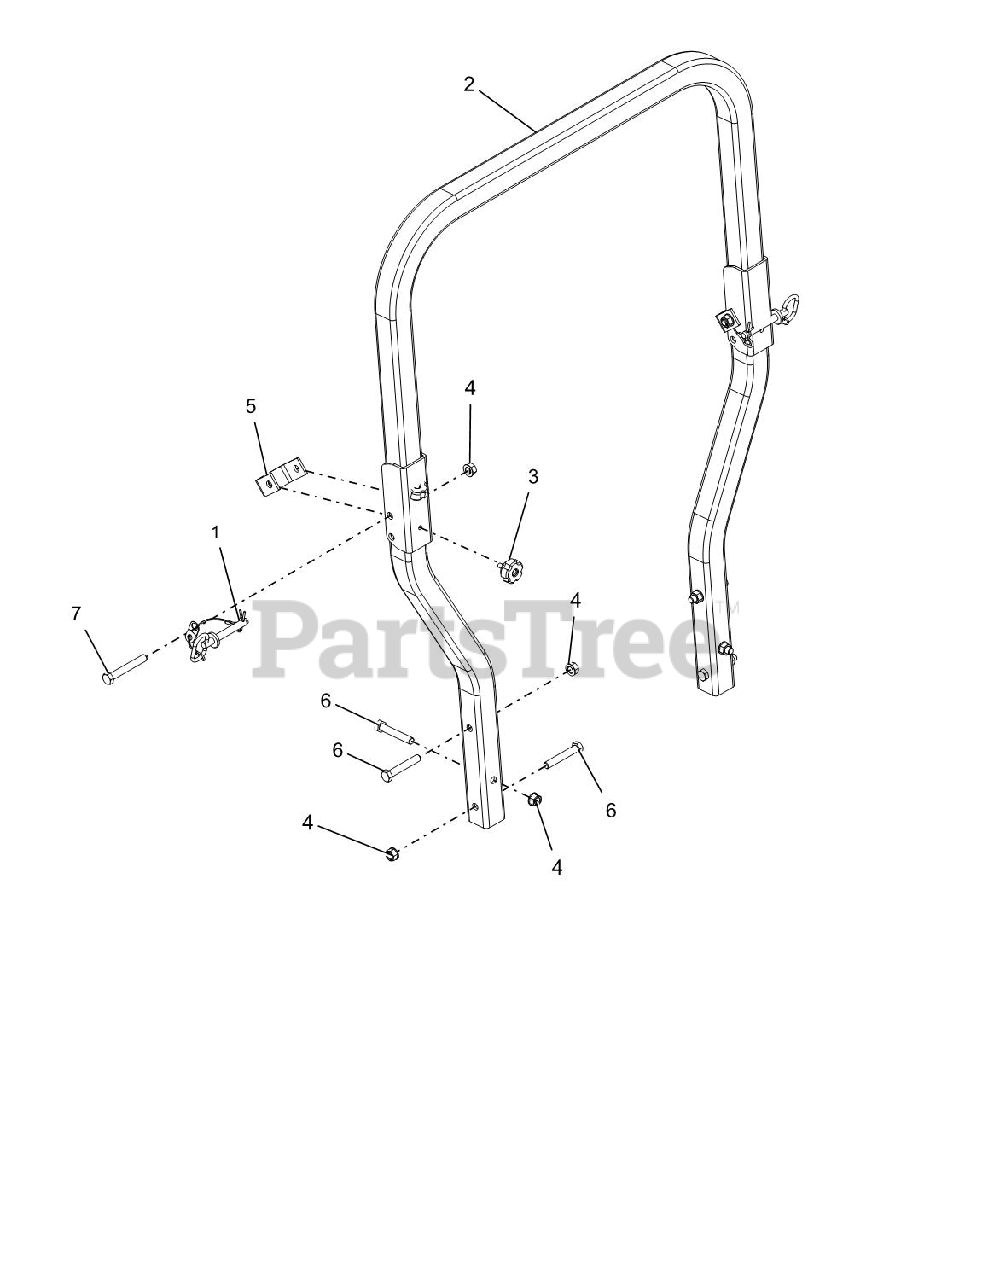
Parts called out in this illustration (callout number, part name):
1	ASSY, ROPS PIN/LANYARD
2	ROPS INCLUDES HOOP RH AND LH SUPPORT
3	KNOB, ROUND 5/16-18 X .750
4	NUT, LK-TOP-FLG .50-13 YWZC
5	BRKT, ROPS STOP
6	BLT-HEX .50-13X3.00 GR5 YWZC
7	BLT-HEX .50-13X3.50 GR5 YWZC
